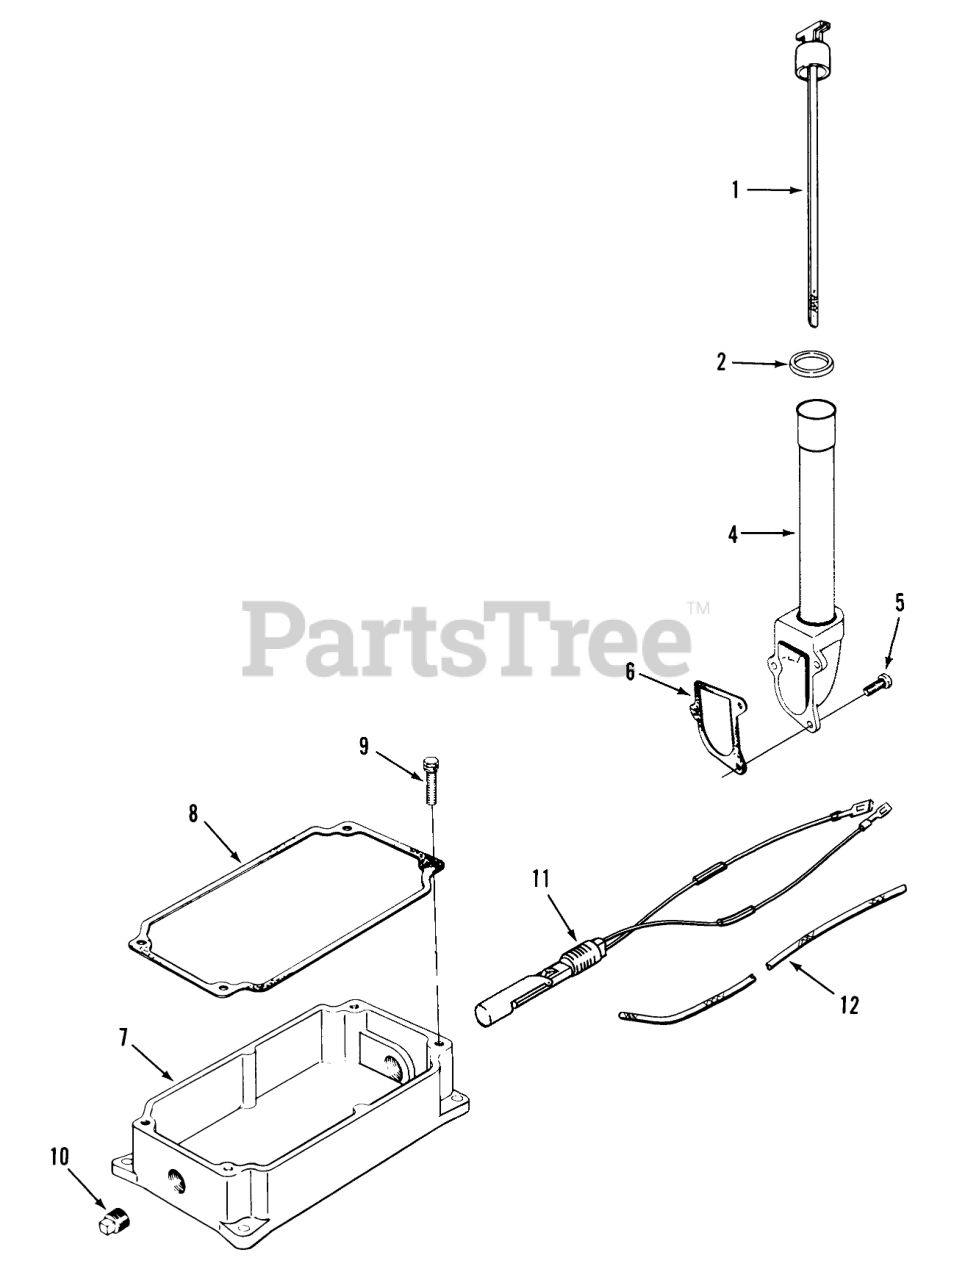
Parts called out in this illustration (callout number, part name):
1	Dipstick
2	0-Ring
4	Adapter-Oil Fill
5	Screw
6	Gasket
7	Oil Pan
8	Gasket
9	Screw
11	Float Switch Kit (Includes Items 12 & Decal)
12	Sleeve
